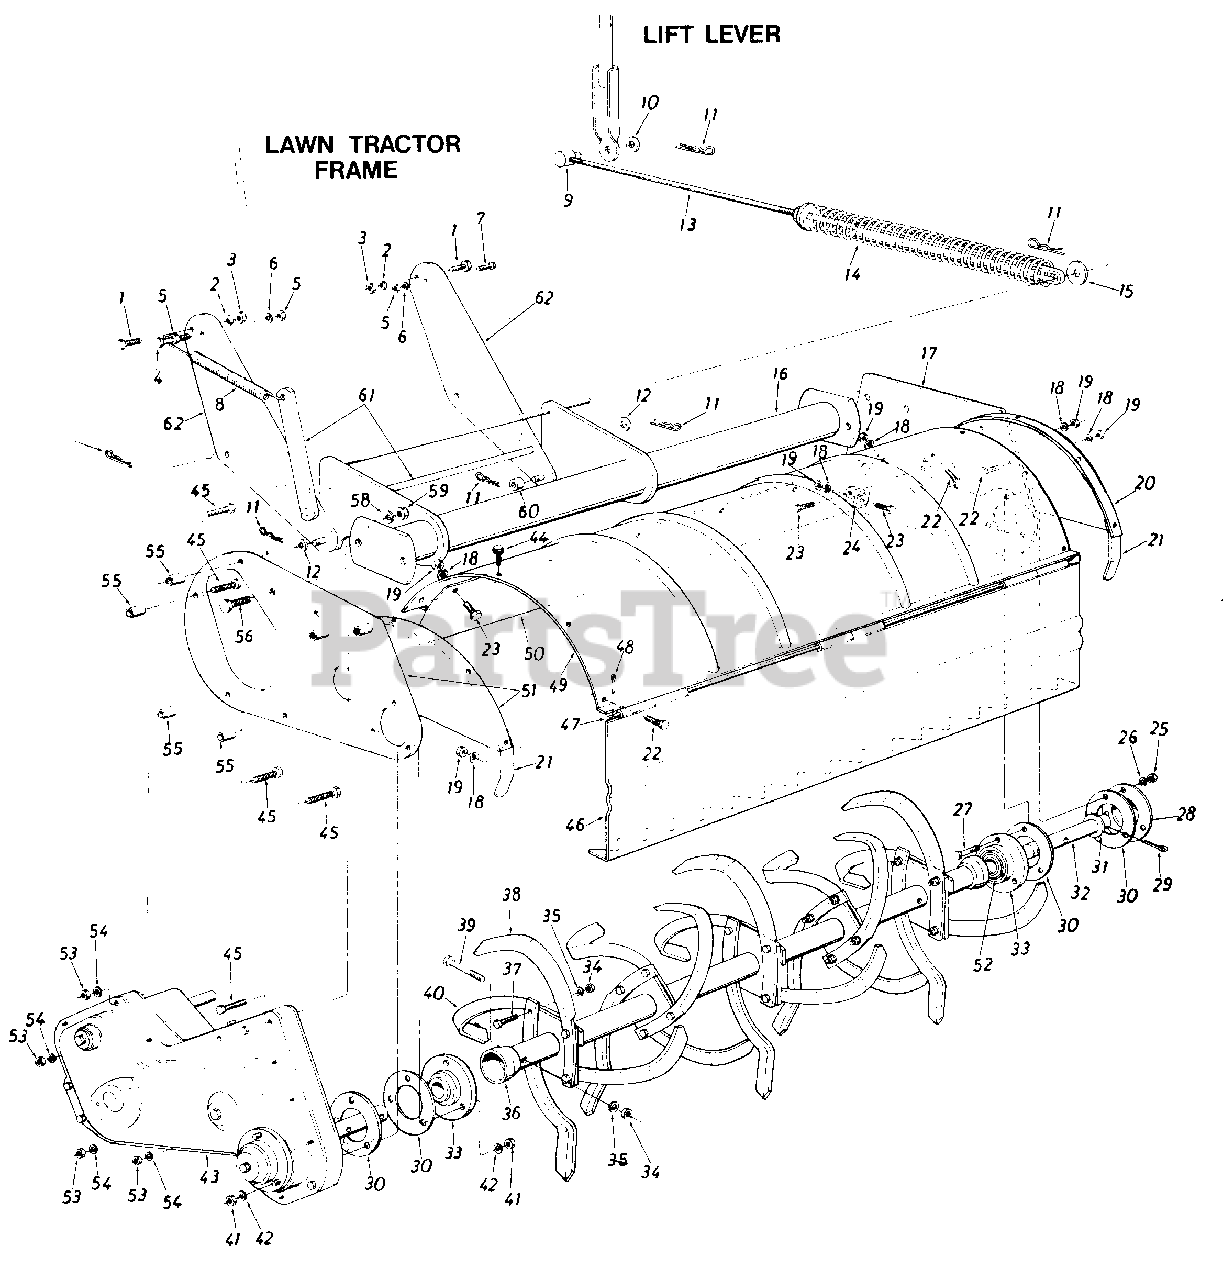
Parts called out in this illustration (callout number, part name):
1	Hex Bolt 3/8-24x .88" Lg.
2	L.-Wash. 3/8" I.D. Heavy Duty
3	Hex Nut 3/8-24 Thd.
4	Hex Bolt 5/16-24 x 1.50" Lg.
5	Hex Nut 5/16-24Thd.
6	L.-Wash. 5/16" I.D.
7	Hex Bolt 5/16-24 x 1.00" Lg.
8	Extension Spring .56" O.D. x 7.75" Lg.
9	Adjustment Ferrule 1/2-13"Thd .
10	Fl.-Wash. .640" I.D. x 1.24" O.D. x .060
11	Intern. Cotter Pin 1/2" Dia.
12	Fl.-Wash. .510" I.D. x 1.0" O.D. x .060
13	Lift Rod Ass'y. 39.0" Lg.
14	Compression Spring 1.50" O.D. x 15.0" Lg.
15	Fl.-Wash. .51" I.D. x 1.50" O.D. x.075
16	Pivot Bracket Assembly
19	Hex Nut5/16-24Thd.
23	Hex Bolt 5/16-24 x .62" Lg.
24	Chute Pivot Bracket
25	Hex Cent. L-Nut 5/16-18 Thd.
26	L.-Wash. 5/16" I.D.
27	Hex Bolt 5/16-18 x 1.0" Lg. (Grade 5)
30	Gasket for Brg. Housing
31	Fl.-Wash. 1.25" I.D. x 2.00" O.D x .06
32	Tine Shaft R. D. 1.25" Dia. x 6.25" Lg.
33	Bearing Housing w/Bearing
34	Hex Nut3/8-24Thd.
35	L.-Wash. 3/8" I.D. Heavy Duty
41	Hex Cent. L.-Nut 5/16-18Thd.
42	L.-Wash. 5/16" I.D.
43	Chain Case Ass'y. Comp.
44	Hex Wash. TT Tap. Scr. 5/16-18 x .62" Lg.
45	Hex Bolt 1/4-20 x 2.75" Lg.
48	Cotter Pin 1/8" Dia. x 1.00" Lg.
53	Hex Nut 1/4-20 Thd.
54	L.-Wash. 1/4" I.D.
55	Spacer.28" I.D. x .62" O.D. x.90" Lg.
56	Hex Bolt 1/2-13 x 1.00" Lg.
58	L.-Wash. 1/2" I.D.
59	Hex Nut 1/2-13 Thd.
60	Spacer .50" I.D. x 1.00" O.D. x.50" Lg.
61	Idler Bracket Support Arm Ass'y.
62	Pivot B racket Support
